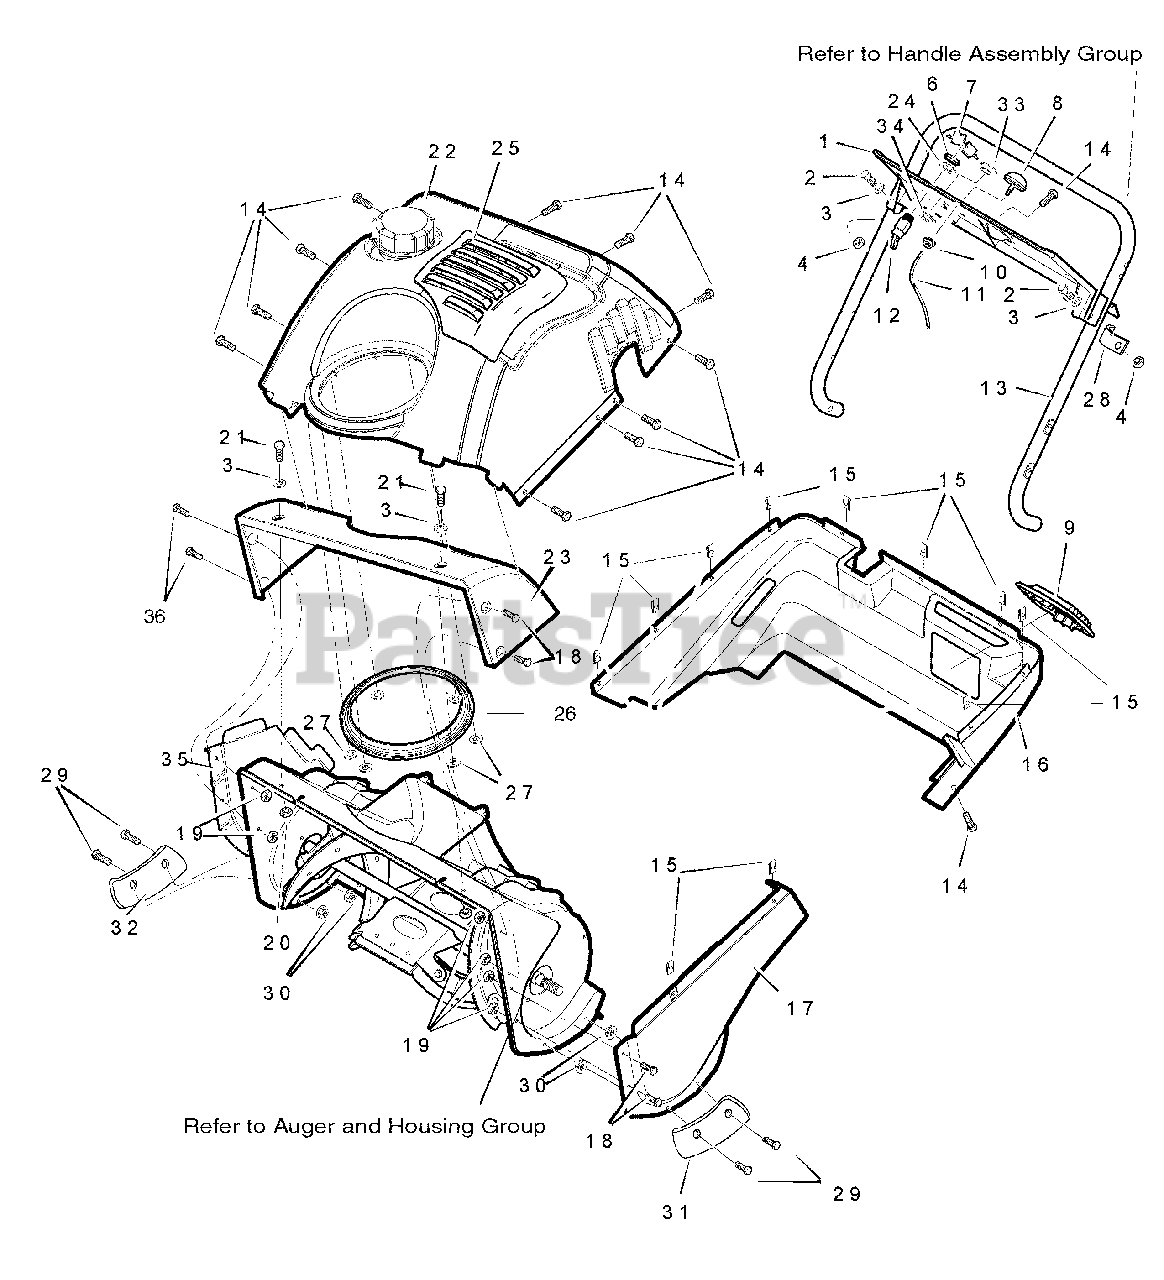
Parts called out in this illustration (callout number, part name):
1	PANEL, Control 22" SS DLR
2	SCREW, 1/4-20 x 1.25
3	WASHER, Flat 9/32 x 5/8 x .065
4	NUT, 1/4-20
6	NUT, 5/8-32
7	KEY, Set
8	PRIMER, Carburetor
9	PANEL, Access 22" SS DLR
10	NUT, Keps 1/4-20
11	HOSE, Primer 9.5"
12	SWITCH, Ignition
13	HANDLE, Lower
14	SCREW, 1/4-14 x 3/4
15	J-NUT, 1/4-10
16	COVER, Bottom 22" SS DLR
17	COVER, Belt 22" SS DLR
18	SCREW, 10-24 x 1/2
19	LOCKNUT, Hex 10-24 Regular Center Lock
20	LOCKNUT, Hex 1/4-20
21	SCREW, 1/4-20 x 5/8
22	COVER, Top 22" SS DLR
23	COVER, Auger Top 22" SS DLR
24	WASHER, Interlock 41/64 x 1.1
25	COVER, Access Oil
26	GASKET, Chute Ring
27	NUT, PUSH
28	CLIP, Cable
29	SCREW, 10-32 x .75
30	NUT, 10-32 Nylock
31	SHOE, Skid L.H
32	SHOE, Skid, R.H
33	ROPE, GROMMET
34	ROPE, GROMMET, Washer
35	COVER, Auger R.H
